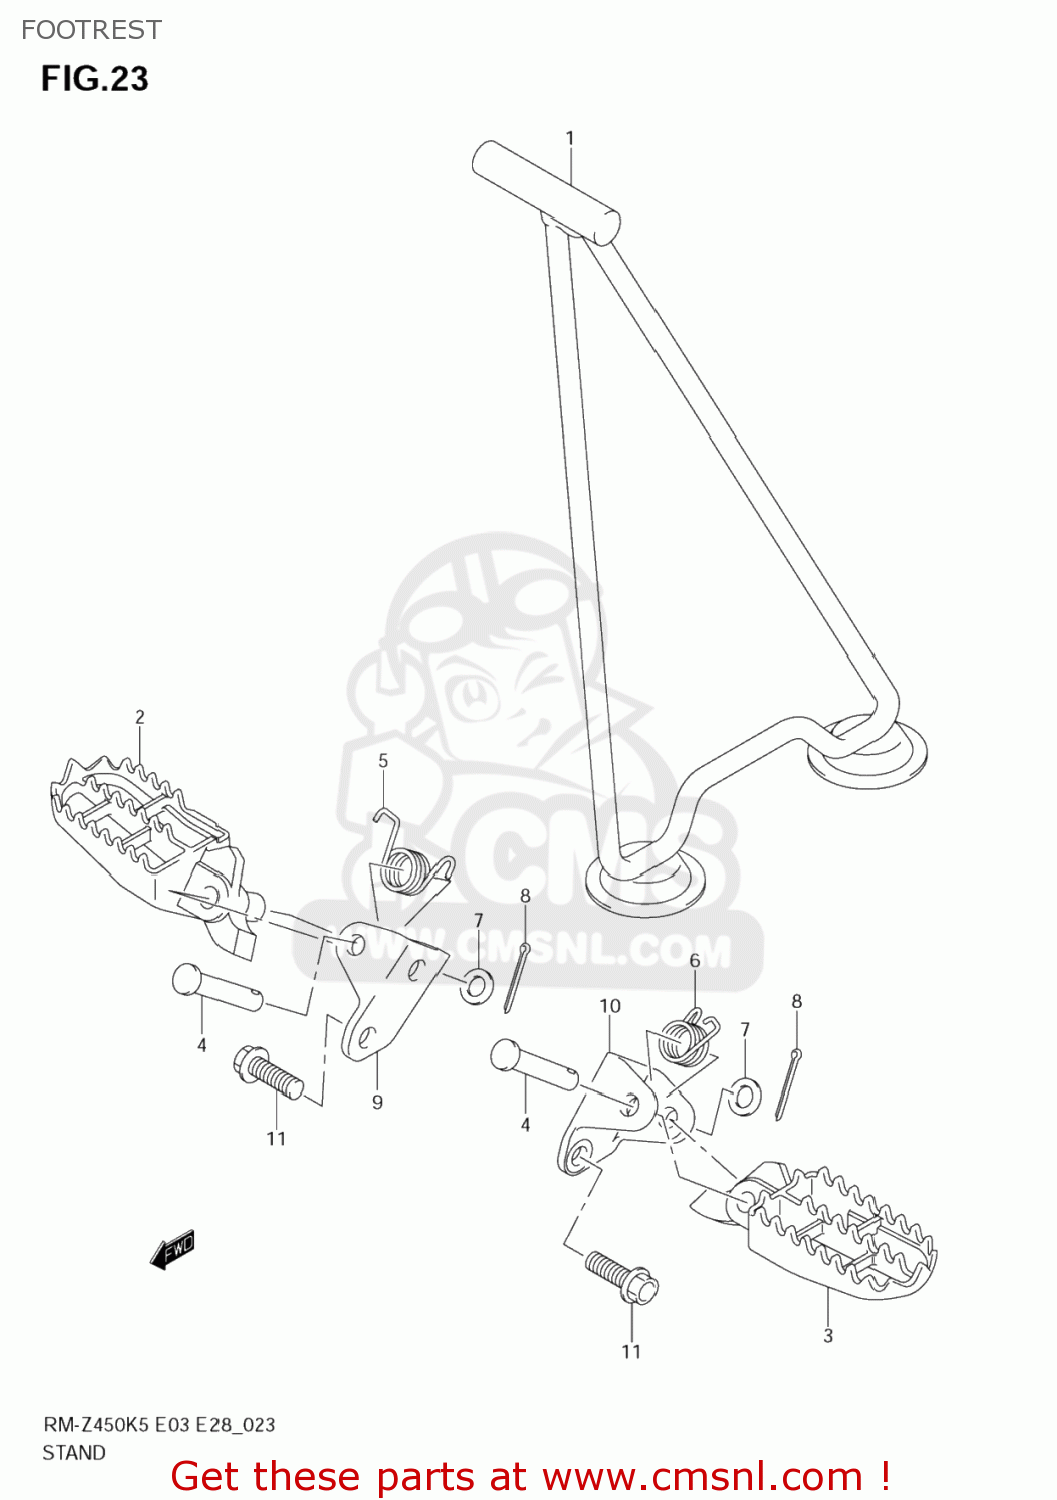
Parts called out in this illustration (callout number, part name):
1	STAND
2	FOOTREST,R
3	FOOTREST,L
4	PIN
5	SPRING
6	SPRING
7	WASHER
8	PIN
9	BRACKET,FOOTREST,R
10	BRACKET,FOOTREST,L
11	BOLT(10X30)
